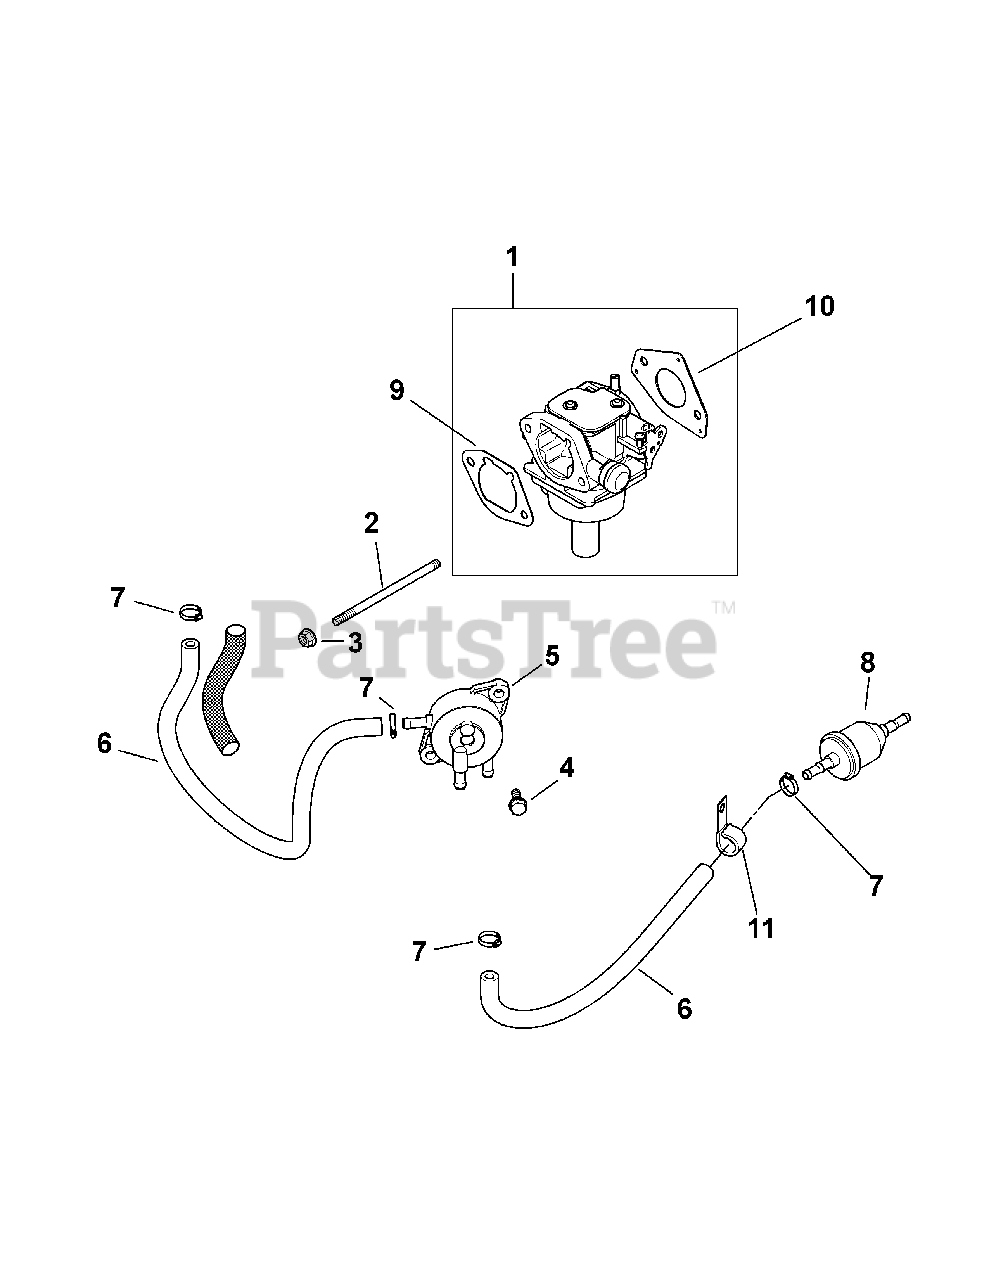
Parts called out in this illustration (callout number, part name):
1	Carburetor Kit
2	Stud, M6 x 1.0 x 106
3	Flange Nut, M6 x 1.0
4	Tap Screw, M6 x 1.7 x 18
7	Hose Clamp, 1/2
9	Air Cleaner Base Gasket
10	Carburetor Gasket
